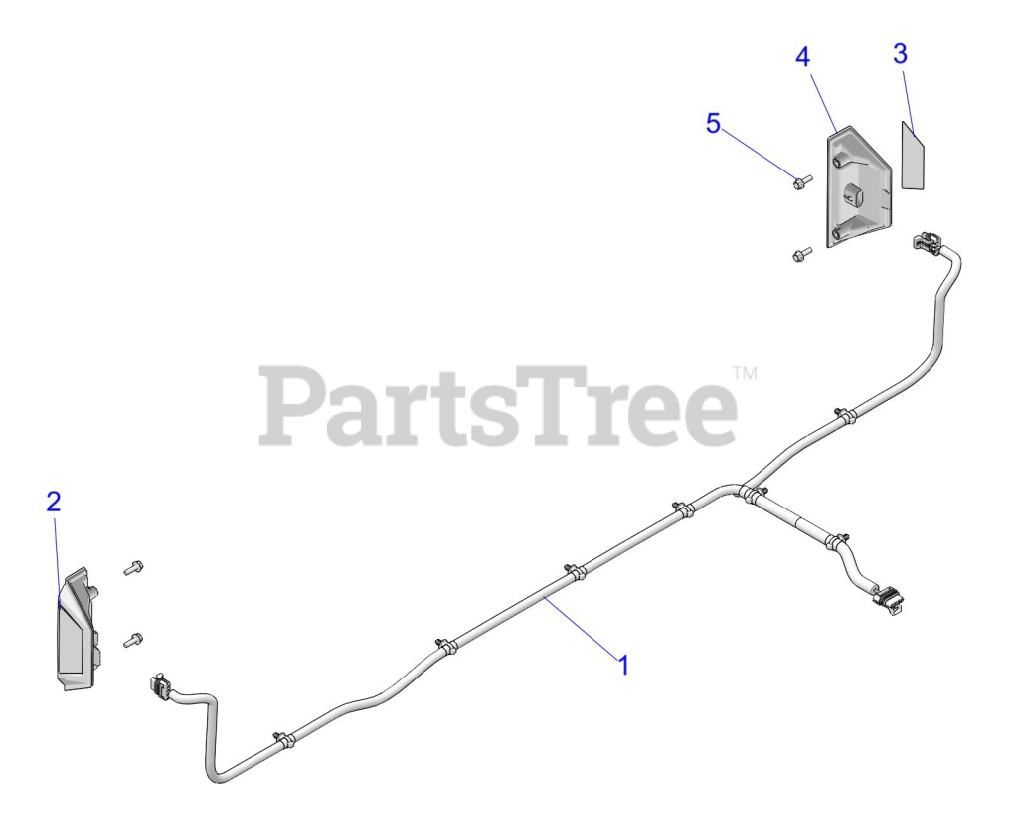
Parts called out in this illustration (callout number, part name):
1	HARNESS- BOX
2	ASM-TAILLIGHT-W/DECAL
3	DECAL-RED REFLECTOR
3	ASM., TAILLIGHT
5	SCR-HXFL-M6X1.0X20 8.8 RIE
